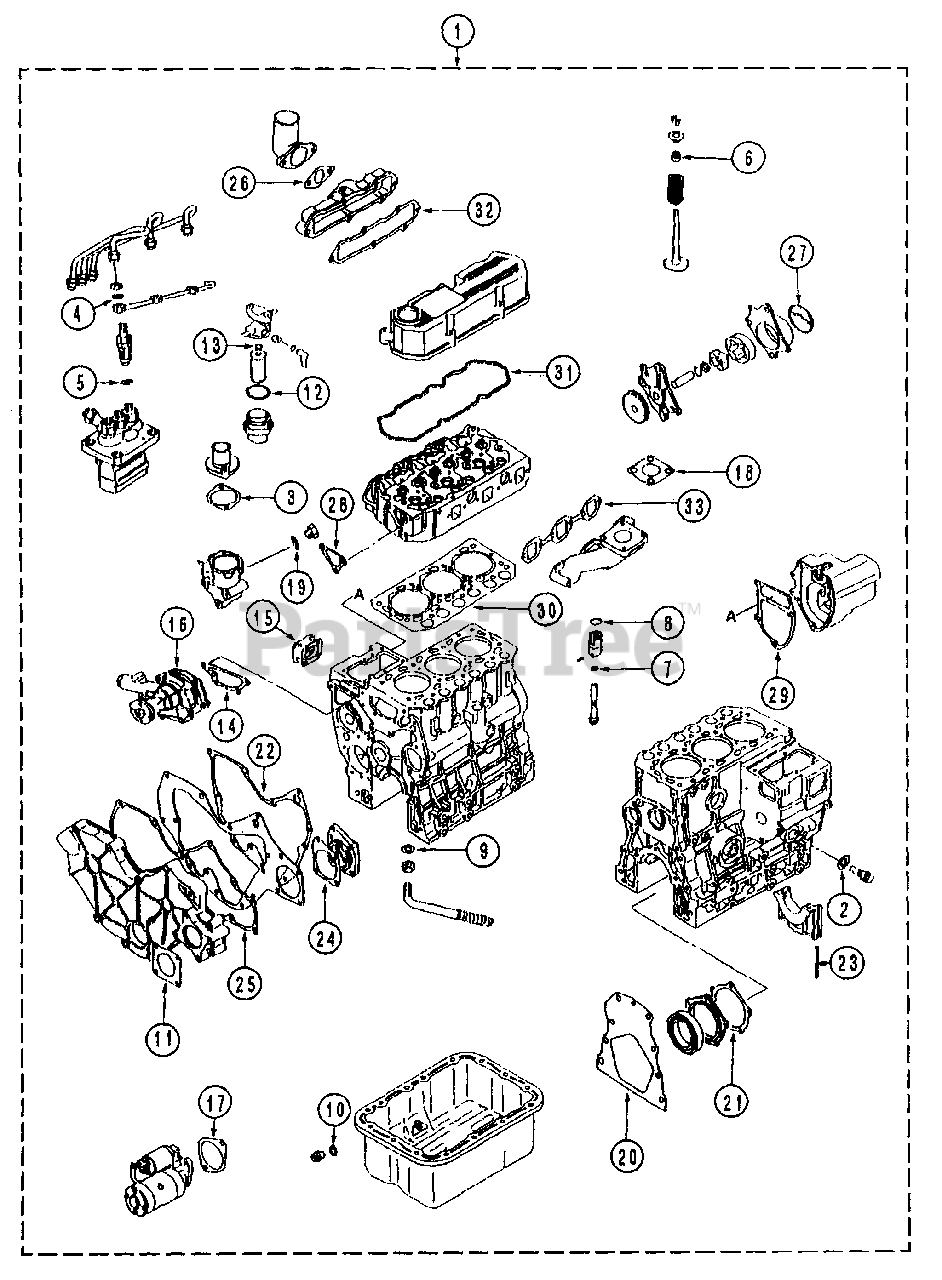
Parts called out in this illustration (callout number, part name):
1	Gasket Kit, (O/H)
3	Gasket
6	Seal, Valve Stem
8	O-Ring
11	Gasket, O/Pump Cover
12	O-Ring
13	O-Ring
14	Gasket, Water Pump
15	Gasket, Tie-Rod Cover
16	Gasket, Water Pump
17	Gasket, Starter
19	Gasket
20	Gasket, Rear Plate
21	Gasket, Oil Seal Case
22	Gasket, Front Plate
24	Gasket, Housing
25	Gasket, Gear
26	Gasket, Inlet
27	Packing, Body
28	Gasket, Thermo Case
29	Gasket, Governor Case
30	Gasket, Cylinder Head
31	Gasket, Rocker Cover
32	Gasket, Inlet Cover
33	Gasket, Exh. Manifold
